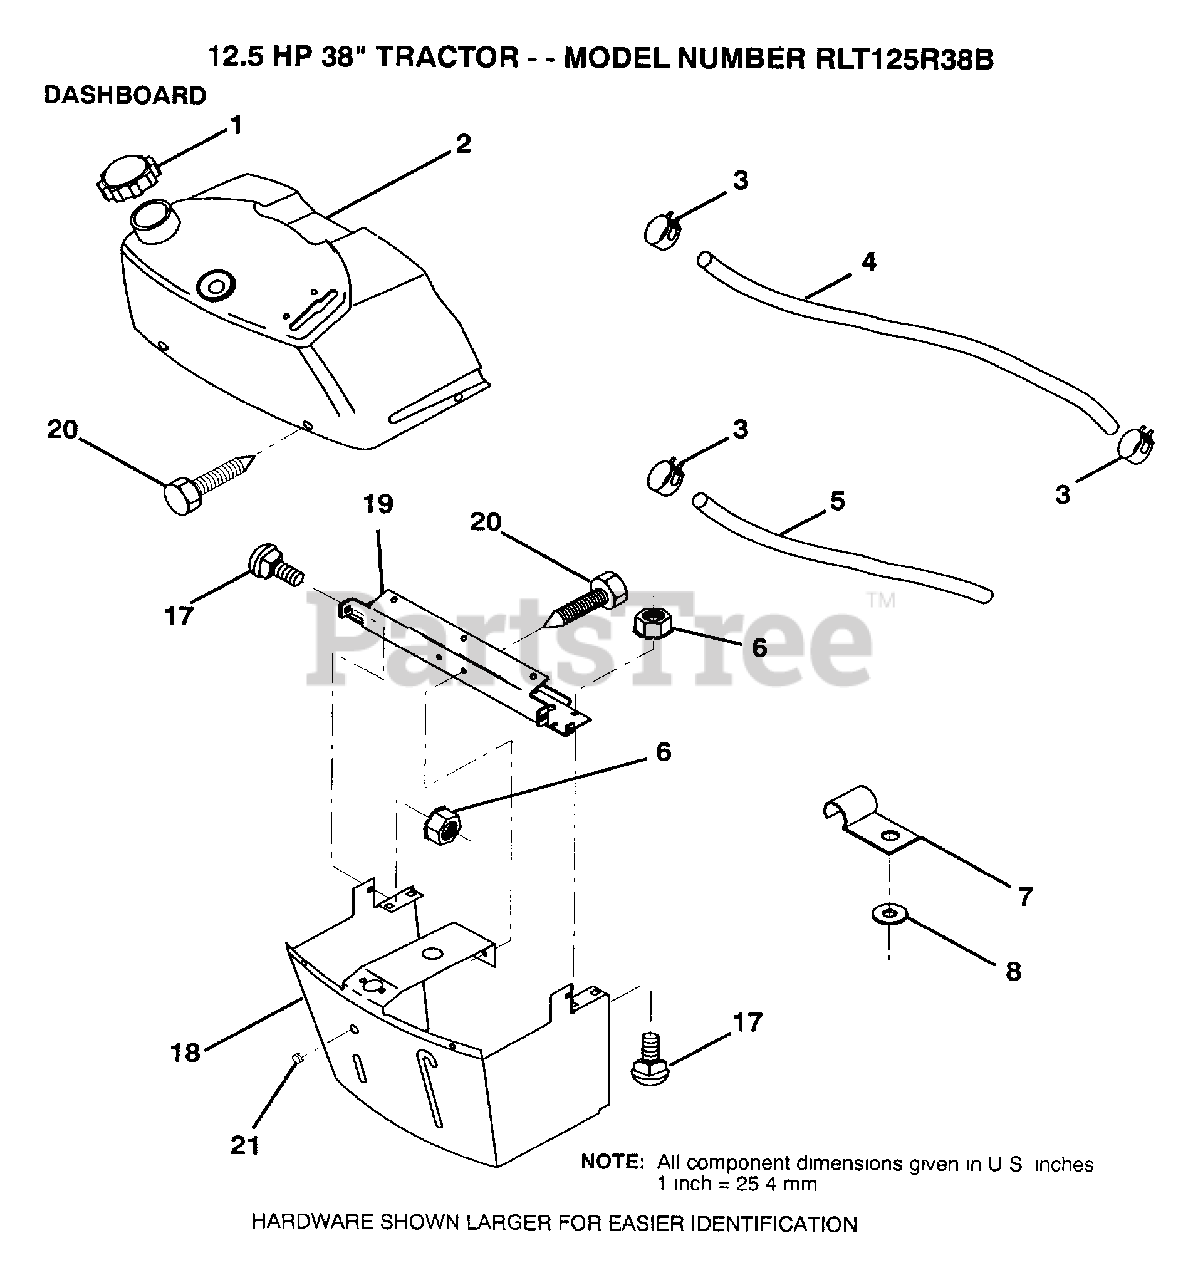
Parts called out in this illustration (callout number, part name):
1	CAP.FUEL.N/VENT
2	TANK.ASM.DASH.LR
3	HOSE CLAMP
5	FUEL LINE T
6	NUT
7	CLIP T
8	WASHER PM
17	BOLT
18	SUPT ASM DASH
19	CROSS BRACE
20	SCREW.1/4-20X1/2
21	PLUG DOME
